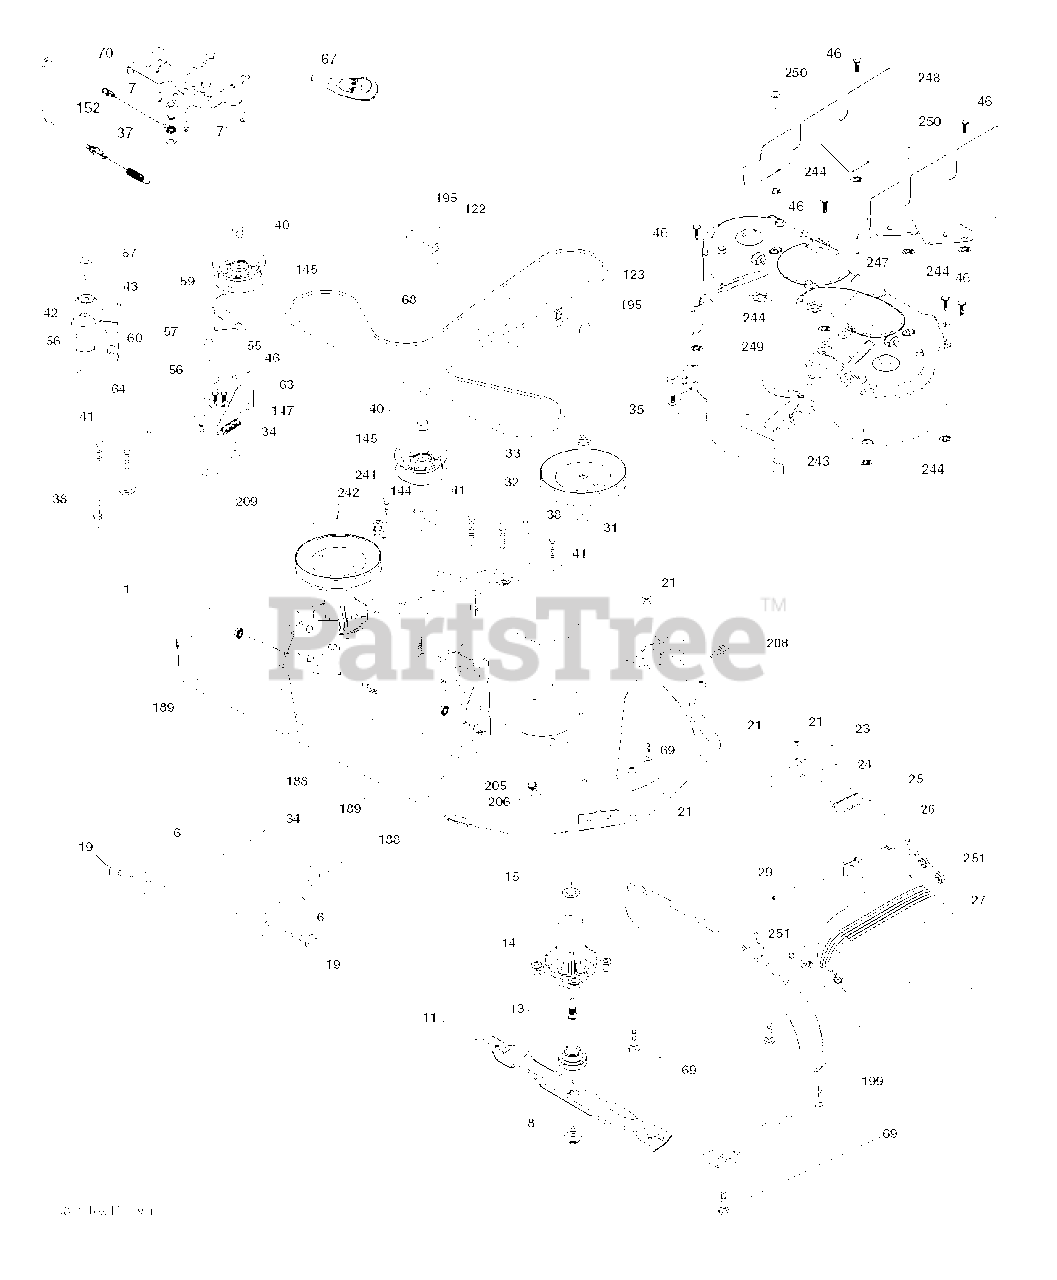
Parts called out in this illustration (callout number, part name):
6	ARM.SUSPENSION.MOWER.R
7	SCREW.#10 X 0.750.BOS THREAD
8	BOLT.WASHER.ASM.7/16-2
11	BLADE 38" PREMIUM
13	SHAFT.ASM.MDRL.N/GREASE.38
14	HOUSING MANDREL
19	BOLT.SHOULDER
21	LOCKNUT
23	BRKT.DEFLECTOR.38"2005+
24	CAP-SLEEVE LT
25	SPRING.TORSION.DEFLECT
26	NUT PUSH M
29	ROD.HINGE
31	WASHER.SPACER.MANDREL
32	PULLEY.MANDREL.5.0.PD.38"
33	NUT.FLANGE.LOCK.TOP
34	BOLT.3/8-16X1.50
35	FASTENER.XMAS.TREE
38	KEEPER BELT LH MANDREL
40	NUT LOCK FLG 3/8-16 UNC
41	Hex Washer Head Bolt, .313-18 X 1.19
42	SPRING.TORSION.BRAKE
43	SRPING.TORSION.RETAINE
46	SCREW.1/4-20X5/8
55	IDLER.ARM
56	SPACER.RETAINER
57	SCREW 3/8-16X1
59	GUARD, BELT
60	ARM BRAKE MOWER RH 38"
63	ARM BRAKE MOWER RH
64	LINK BRAKE
67	HANDLE.CLUTCH.CABLE.LT
69	BOLT
70	CLUTCH.ASM.MANUAL.LT.PRED
122	KEEPER BELT ENGINE LH
123	KEEPER BELT RH
144	KEEPER BELT
145	PULLEY.IDLER.48"PRIMARY
147	SPRING RETURN
152	CABLE.CLUTCH.MANUAL.
188	STUD.FASTNER.W/ANTI-ROTATE
189	NUT LOCK HEX FLANGE 5/16-18
195	SCREW, 3/8-16X3/4
199	BAFFLE VORTEX
205	SCREW
208	SCREW 3/8-16X1/2
209	WASHER 12/32X2X10GA
242	PORT.WASHOUT
244	PALNUT 1/4
